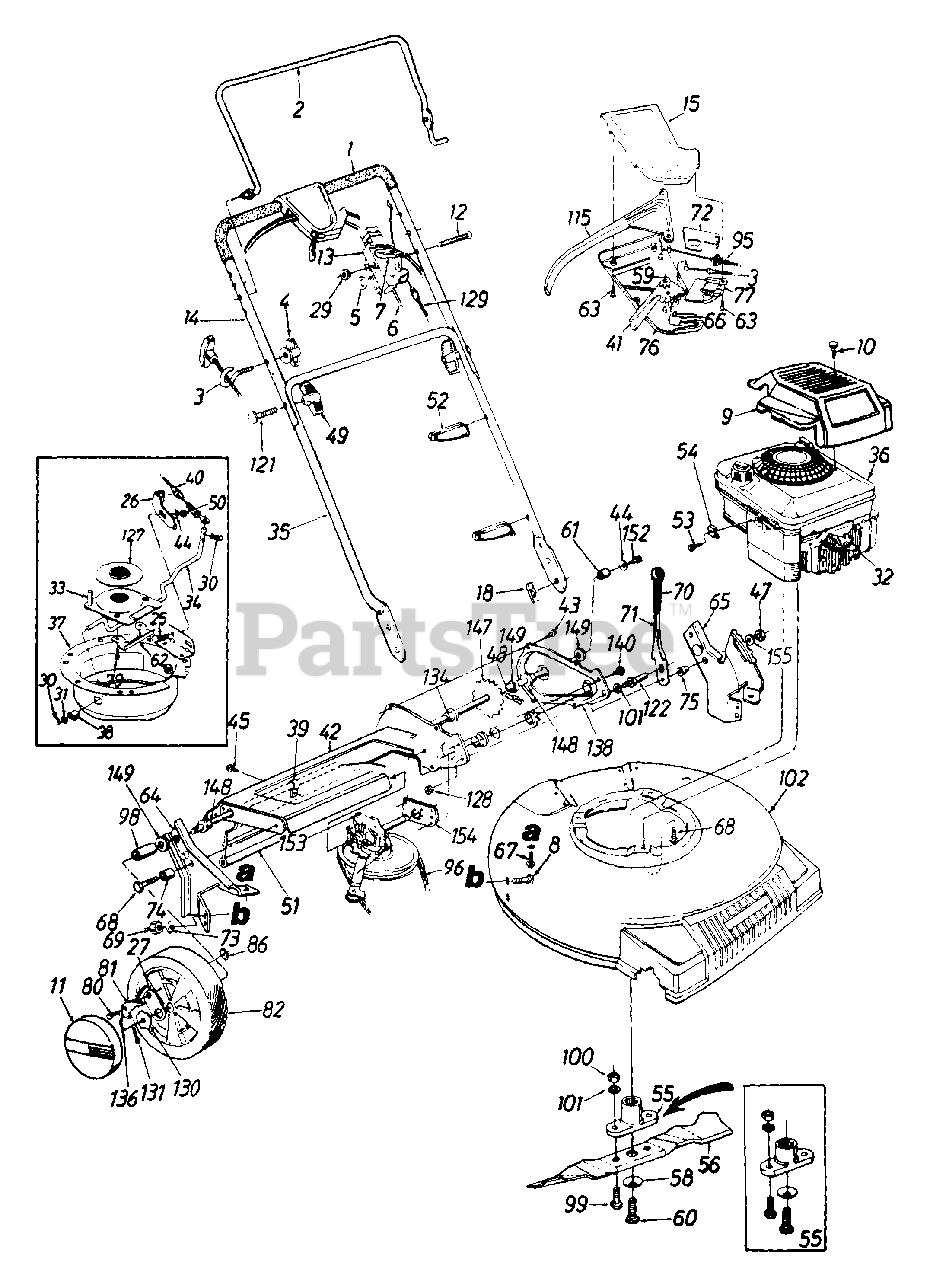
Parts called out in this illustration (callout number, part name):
1	Grip
2	Control Handle
3	Rope Guide
4	Wing Nut 1/4-20 Thd.
5	Curved Spring Wash..66" I.D
6	Throttle Wire - 55" Lg.
7	Throttle Lever
8	Carriage Bolt 5/16-18 x .62" Lg.
9	Engine Shroud
10	Hi-Lo Screw #10 x 1.25" Lg.
11	Hub Cap
12	Oval C-Sunk Mach. Scr.
13	Throttle Body
15	Upper Control Housing
18	Internal Cotter Pin 5/16" Dia.
29	Hex L-Nut 1/4-20 Thd,
30	Cotter Pin 3/32" Dia. x .75"
31	Fl-Wash..328" I.D. x.68"
32	Spark Plug Insulator
33	Lower Pulley Half Ass'y.
34	Shift Rod
36	Engine
39	Clamp
40	6 Spd. Cable
41	6 Spd. Shift Lever
44	Bell-Wash. 1/4" I.D.
45	Truss Mach. B-Tap Scr. #10 x .5"
47	Hex Patch L-Nut 3/8-24 Thd.
48	#48 Chain .500" Pitch x 38 Links
49	Hand Knob
50	Hex L-Nut 1/4-20 Thd.
51	Rear Flap 3.75" x 17.5" Lg.
52	Cable Tie
53	Hex Wash. Hd. Scr. #10-32 x .62" Lg.
54	Casing Clamp
55	Blade Adapter Kit
56	21" Mulching Blade
58	Bell-Wash..47" I.D. x 1.14" O.D.
59	Gear Insert
60	Hex Bolt 7/16-20 x 2.5"
61	Spacer .513" I.D.
67	Hex 8-Tap Scr. 5/16-18
68	Hex TT-Tap Scr 3/8-16
69	Hex Nut 5/16-18 Thd
71	Height Adj. Lever
72	6 Spd. Rack Cable Brkt
73	Bell-Wash. 5/16" I.D.
74	Spacer .383" I.D.
75	Shld. Spacer 5" Dia.
76	Lower Control Housing
77	Cable Mounting Cap
79	Hex Wash
80	Shld. Scr. 342" Dia. x .268
81	Pawl
82	Wheel Ass'y. Comp
86	Weld Top L-Nut 1/4-20 Thd.
95	S.P. Cable
96	"Y"-Belt
98	Sleeve 526" I.D.
99	Hex Bolt 3/8-24 x 1.0" Lg.
100	Hex Nut 3/8-24 Thd.
101	L-Wash 3/8" I.D
121	Curved Hd. Bolt 5/16-18 x 2" Lg.
122	Shld. Pin 1.43" Lg.
127	Pulley Half - Serrated
128	Hex Jam Nut 3/8-24 Thd
129	Control Cable - 39"
130	Ratchet Wheel 1.62" O.D.
131	Cotter Pin 1/8" Dia. x 1"
134	Hex Flange Bearing
136	Spring - Nylon
147	Rear Shaft Ass'y. 21.44" Lg.
148	Hex Flange Brg..506" I.D.
149	Fl-Wash..531" I.D. x .930"
152	Hex Bolt 1/4-20 x .62" Lg. (Grade 5)
153	Transmission Comp. (See Breakdown)
155	Fl-Wash..385" I.D. x .87" O.D.
